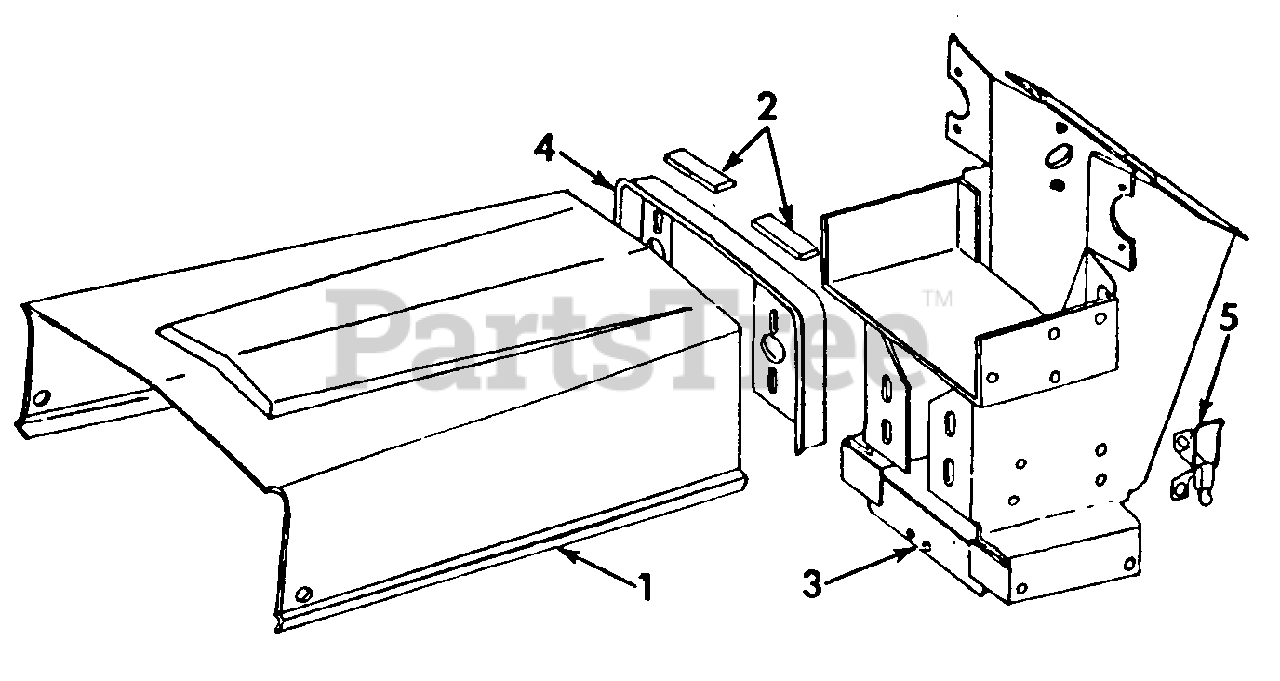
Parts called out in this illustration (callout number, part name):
2	Pad, Hood Bumper
3	Pedestal Assy
4	Support, Rear Hood
5	Latch Assy, Hood
